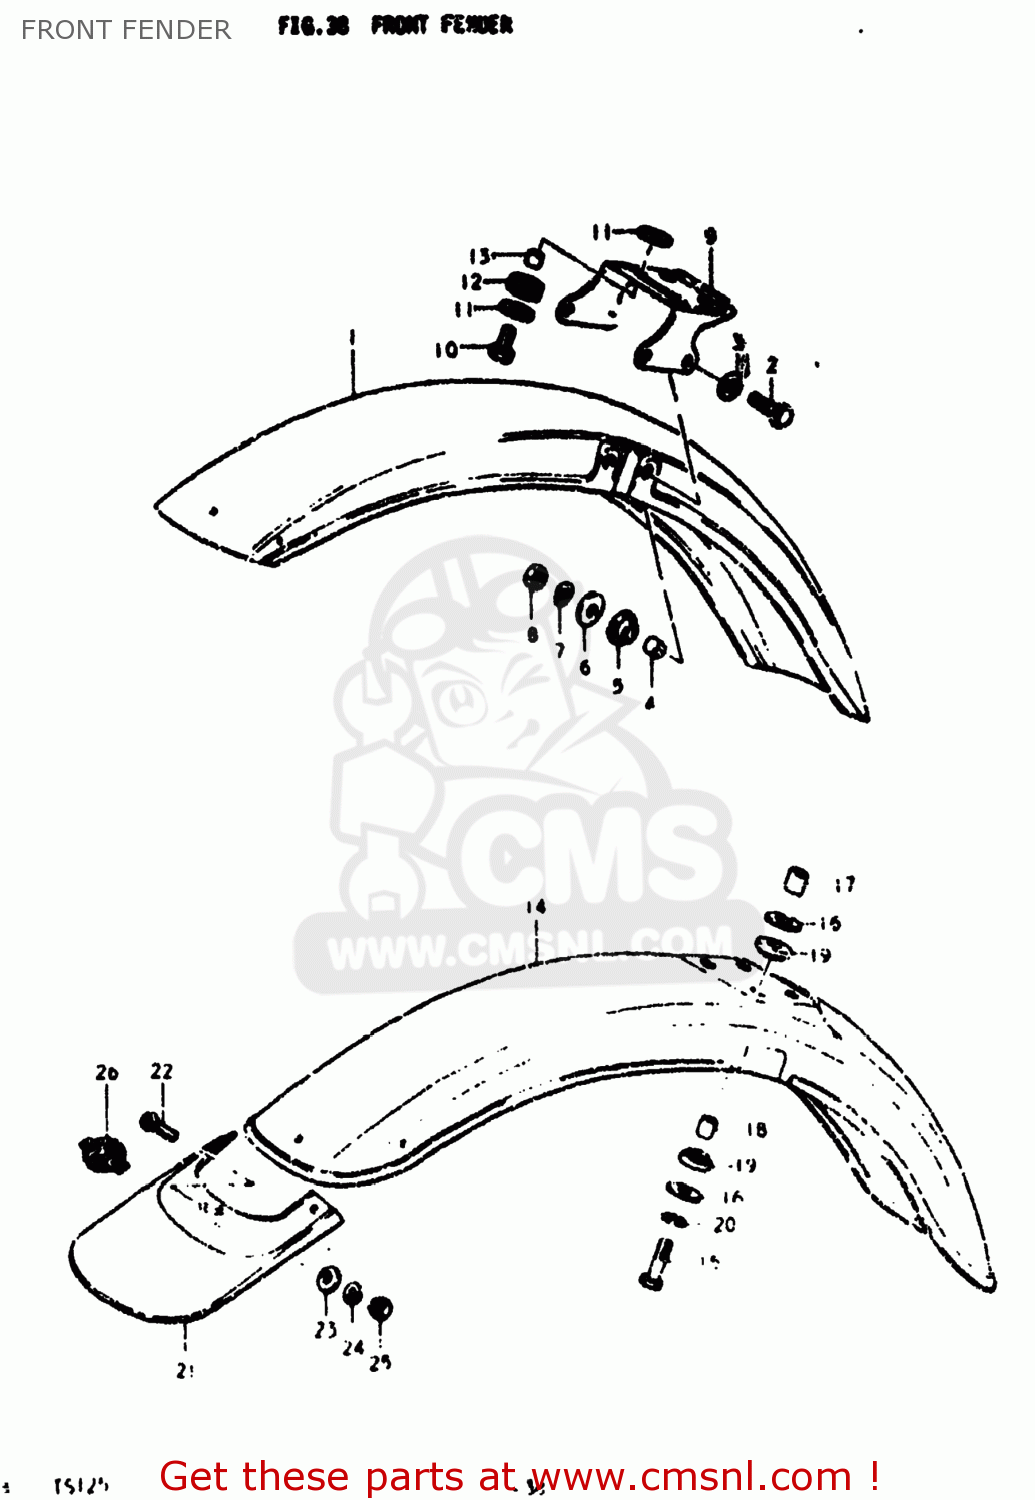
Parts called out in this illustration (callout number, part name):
1	FENDER,FRONT
2	BOLT(6X18)
3	WASHER, LOWER
4	WASHER (5.1X20X1.4)
5	CUSHION
6	WASHER (6.5X20X1.2)
7	LOCK WASHER
8	NUT
9	BRACE,FRONT FENDER
10	BOLT
11	WASHER (6.5X20X1.2)
12	CUSHION
13	SPACER(6.1X9X7.5)
14	FENDER,FRONT
15	BOLT
16	WASHER (6.5X24X1.2)
17	SPACER (6.5X10.5X13.5)
18	SPACER (6.5X10.5X13.5)
19	CUSHION
20	LOCK WASHER
21	MUD FLAP,FRONT FENDER
22	SCREW
23	WASHER
24	LOCK WASHER
25	NUT
